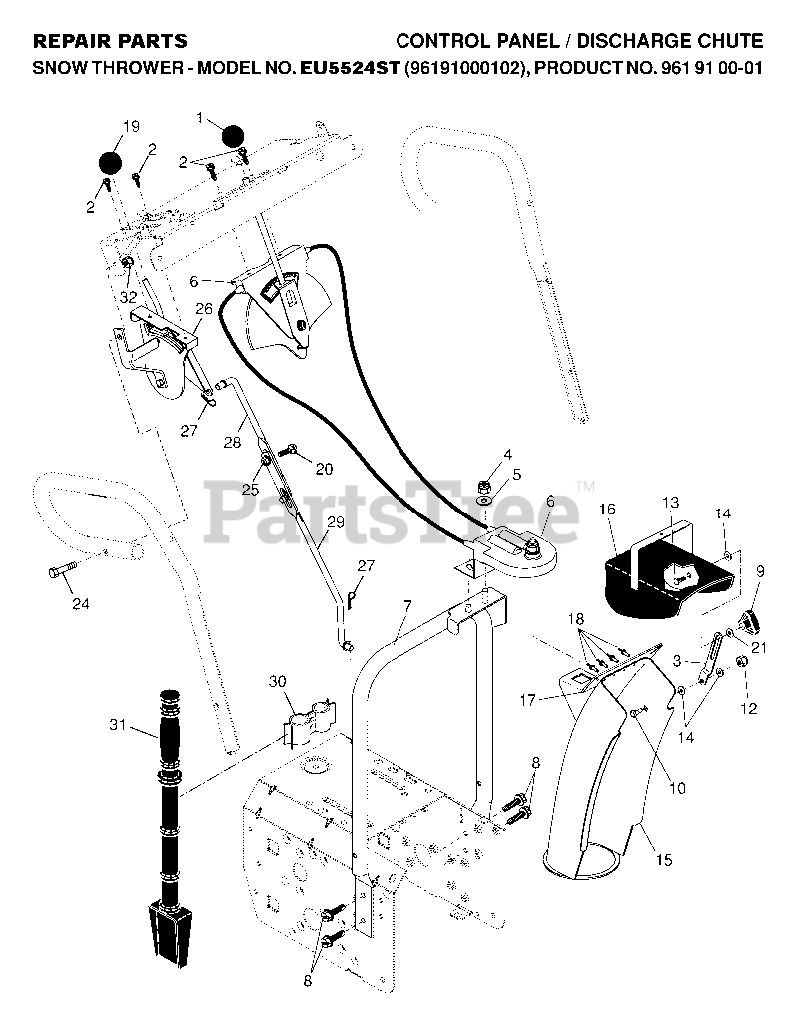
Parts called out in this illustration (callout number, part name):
1	KNOB, LEVER
2	SCREW #10-24 X 5/8
3	STRAP, CHUTE
4	NUT
5	WASHER
6	CONTROL ASSEMBLY,CHUTE ROTATER
7	SUPPORT, PIVOT
8	SELF-TAPPING SCREW 5/16-18X3/4
9	KNOB, DEFLECTOR
10	SHOULDER BOLT
12	NUT.HEX.FLANGE.1/4
13	BOLT
14	WASHER, NYLON FRICTION
15	CHUTE ASSEMBLY
16	DEFLECTOR.WELDMENT.PNT.ORANGE
17	SEAL, DEFLECTOR
18	RIVET BLIND
19	RP KNOB, SPEED CONTROL LEVER
20	BOLT
21	WASHER.20X8.5
25	NUT, HEX FLANGE 5/16-18
26	HEAD ASSY SPEED
27	SPRING RETAINER
28	ROD, UPPER SPEED CONTROL
29	ROD, LOWER SPEED CONTROL.SNOW
30	CLAMP.ASM.CLEANOUT.TOOL.SNOW
31	CLEAN OUT TOOL
32	NUT.LOCK.5/16-18
